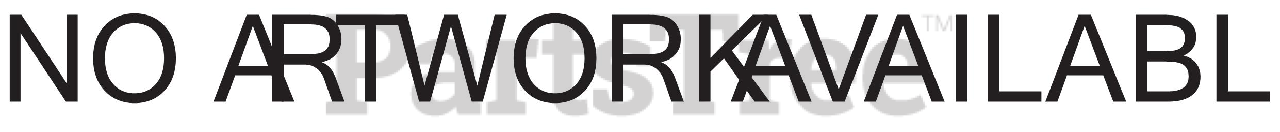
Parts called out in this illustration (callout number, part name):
2	SCREW 1/4-20 X 2.50 GR5
3	FLANGE LOCK NUT
4	CABLE TIE 7"
6	FLAT WASHER
7	ADJUSTMENT BAR
